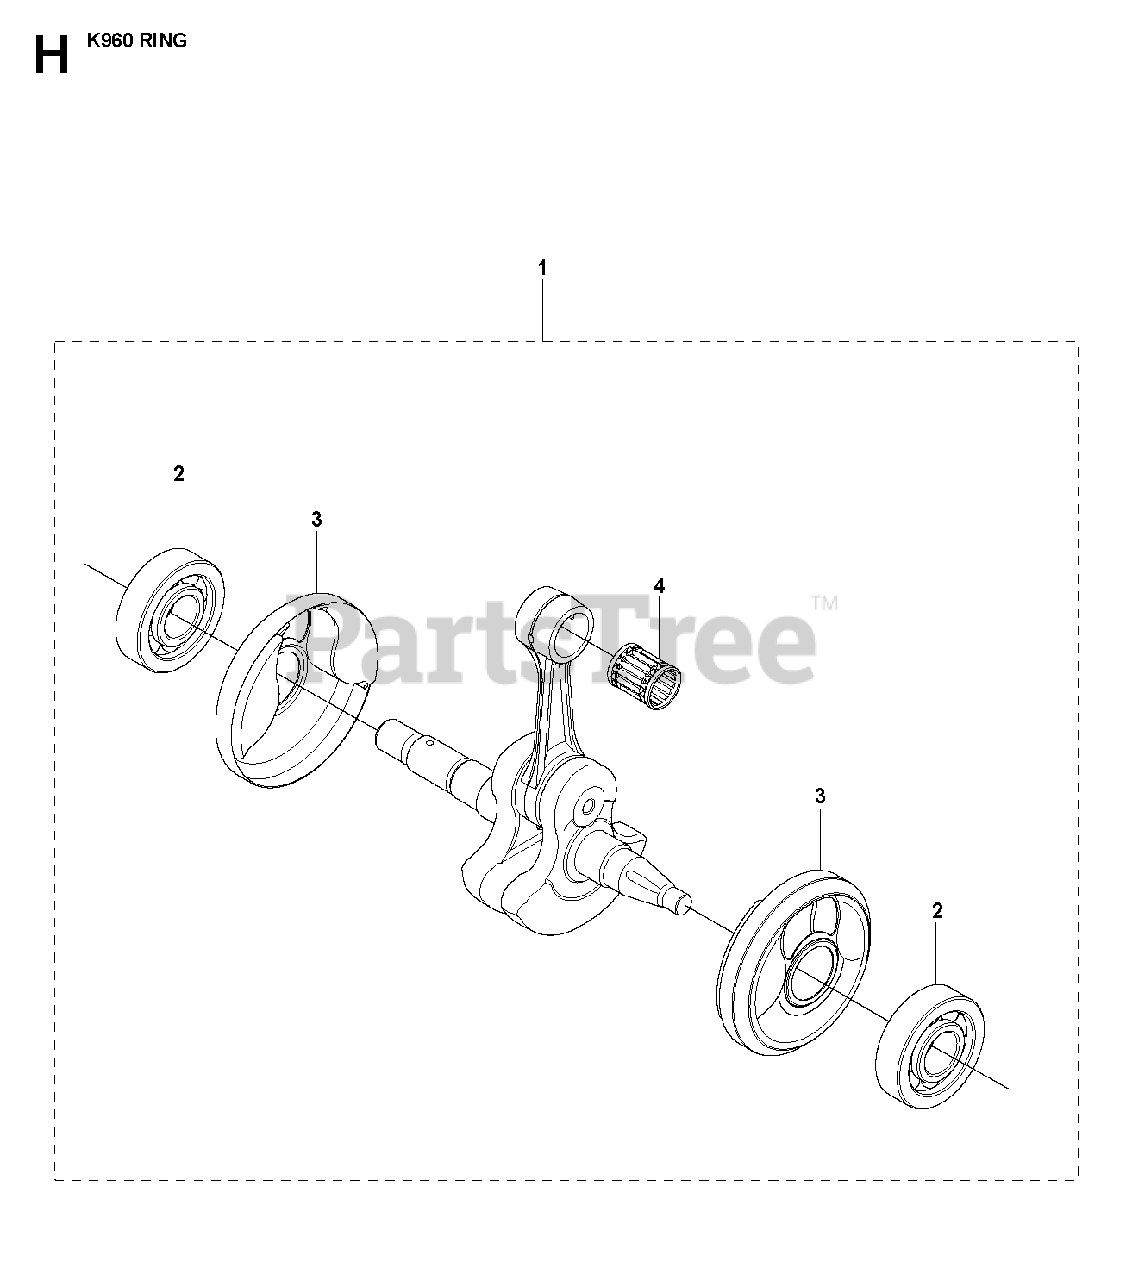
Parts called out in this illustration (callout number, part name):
1	CRANKSHAFT ASSYIncl. 2 - 4
2	BALL BEARING
4	NEEDLE BEARING
